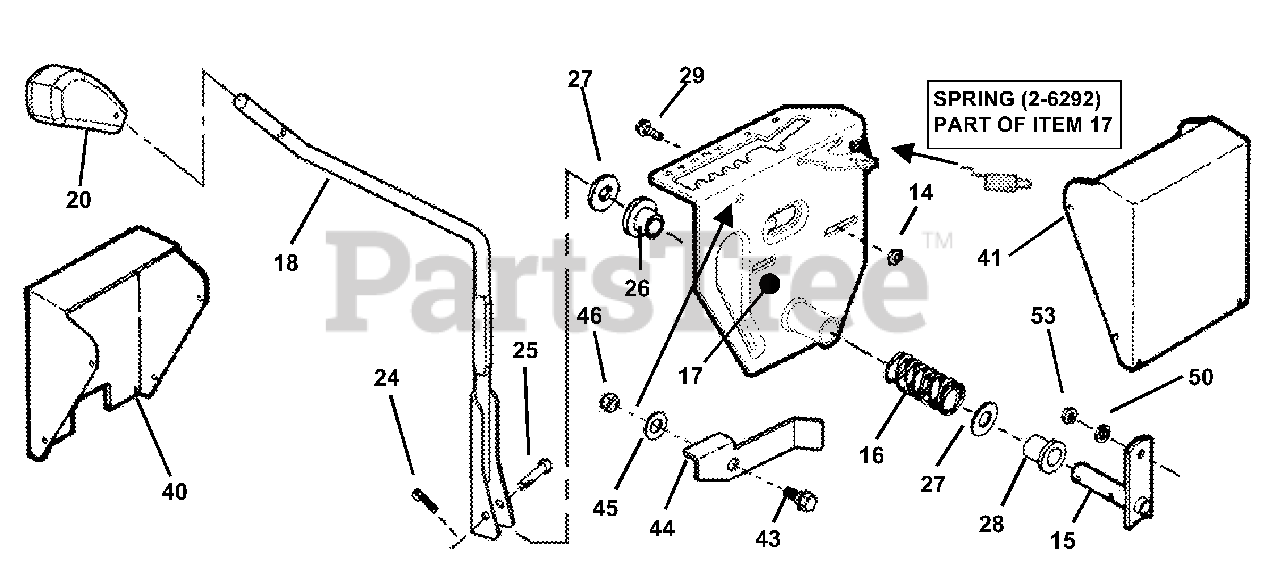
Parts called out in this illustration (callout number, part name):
14	NUT, 5/16-18 Hex, Gr. 5 or B
15	ARM, Shift Handle (weldment)
16	SPRING, Shift Handle
17	ASSEMBLY, Shift Detent
18	HANDLE, Shift (weldment)
20	GRIP, Shift Handle
24	PIN, 3/32 x 3/4" Cotter
25	PIN, 1/4 x 1-3/4" Tapered Clevis
26	BUSHING, Nylon
27	WASHER, Thrust
28	BUSHING, Nylon
29	SCREW, 5/16-18 x 5/8" Self Tap
40	COVER, Switch
41	COVER, Battery
43	BOLT, 5/16-18 Shoulder
44	LEVER, Over-Ride
45	WASHER, 7/16" Flat
46	NUT, 5/16-18 Nyloc
50	WASHER, 5/16" Split Lock
53	NUT, 5/16-24 Hex, Grade 5
